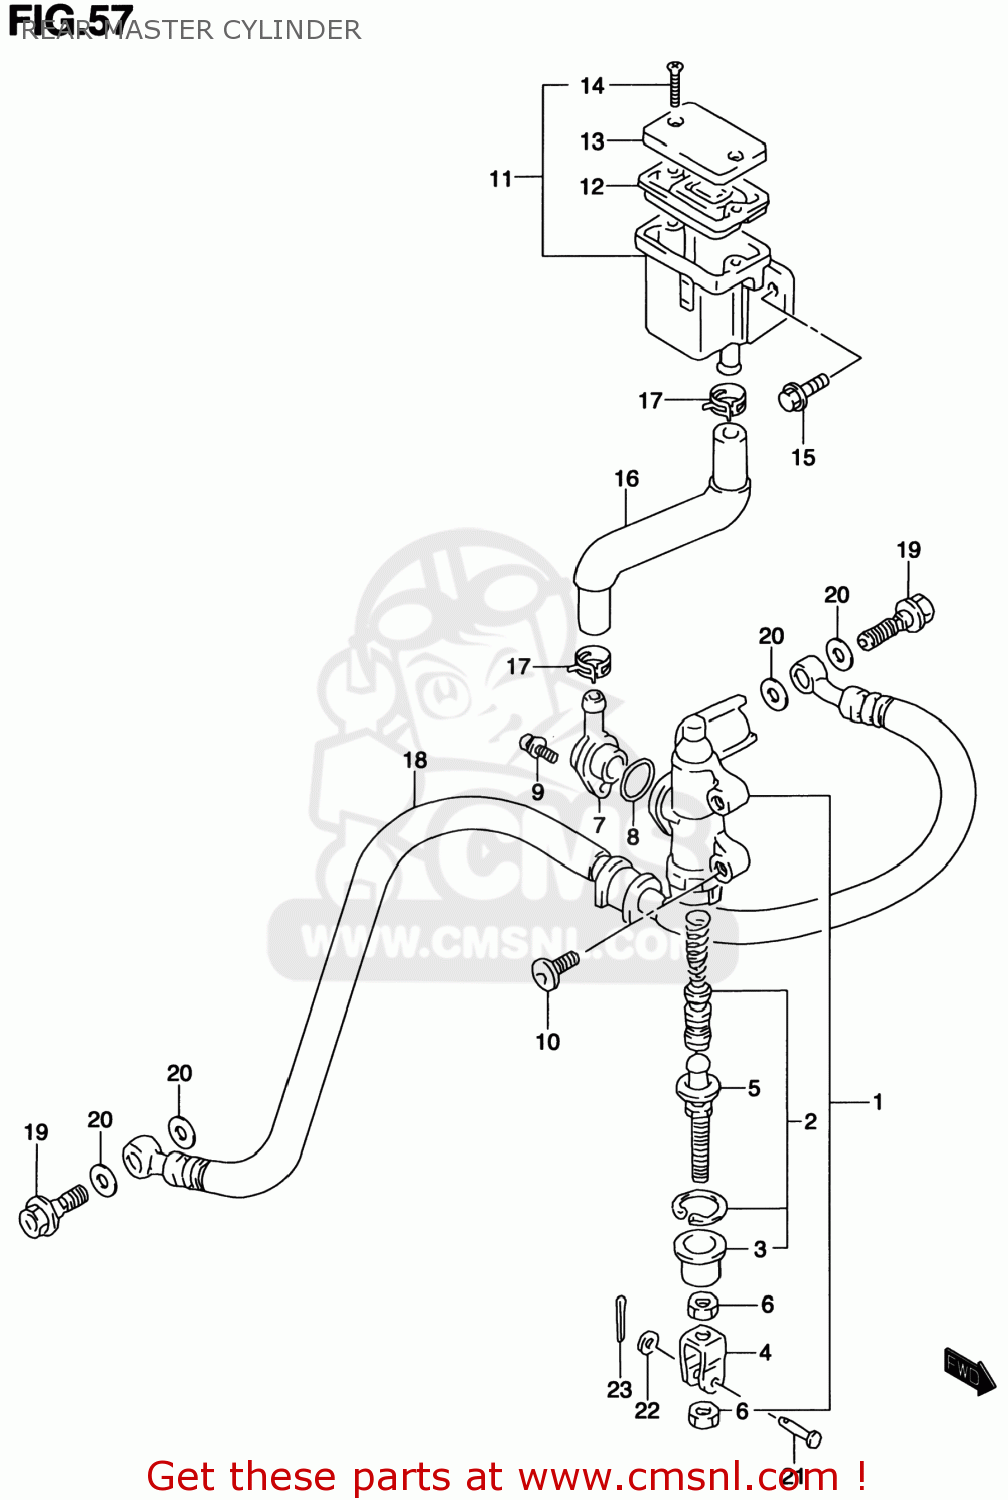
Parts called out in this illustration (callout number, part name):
1	CYLINDER ASSY,RR MASTER
2	PISTON/CUP SET
3	BOOT
4	YOKE
5	ROD,PUSH
6	NUT
7	CONNECTOR
8	O RING
9	SCREW
10	SCREW(6X25)
11	TANK ASSY,RESERVOIR
12	DIAPHRAGM
13	CAP
14	SCREW
15	BOLT
16	HOSE,RESERVOIR TANK
17	CLIP
18	HOSE,RR BRAKE
19	BOLT UNION
20	WASHER(10X15X1.5)
21	PIN
22	WASHER
23	PIN
